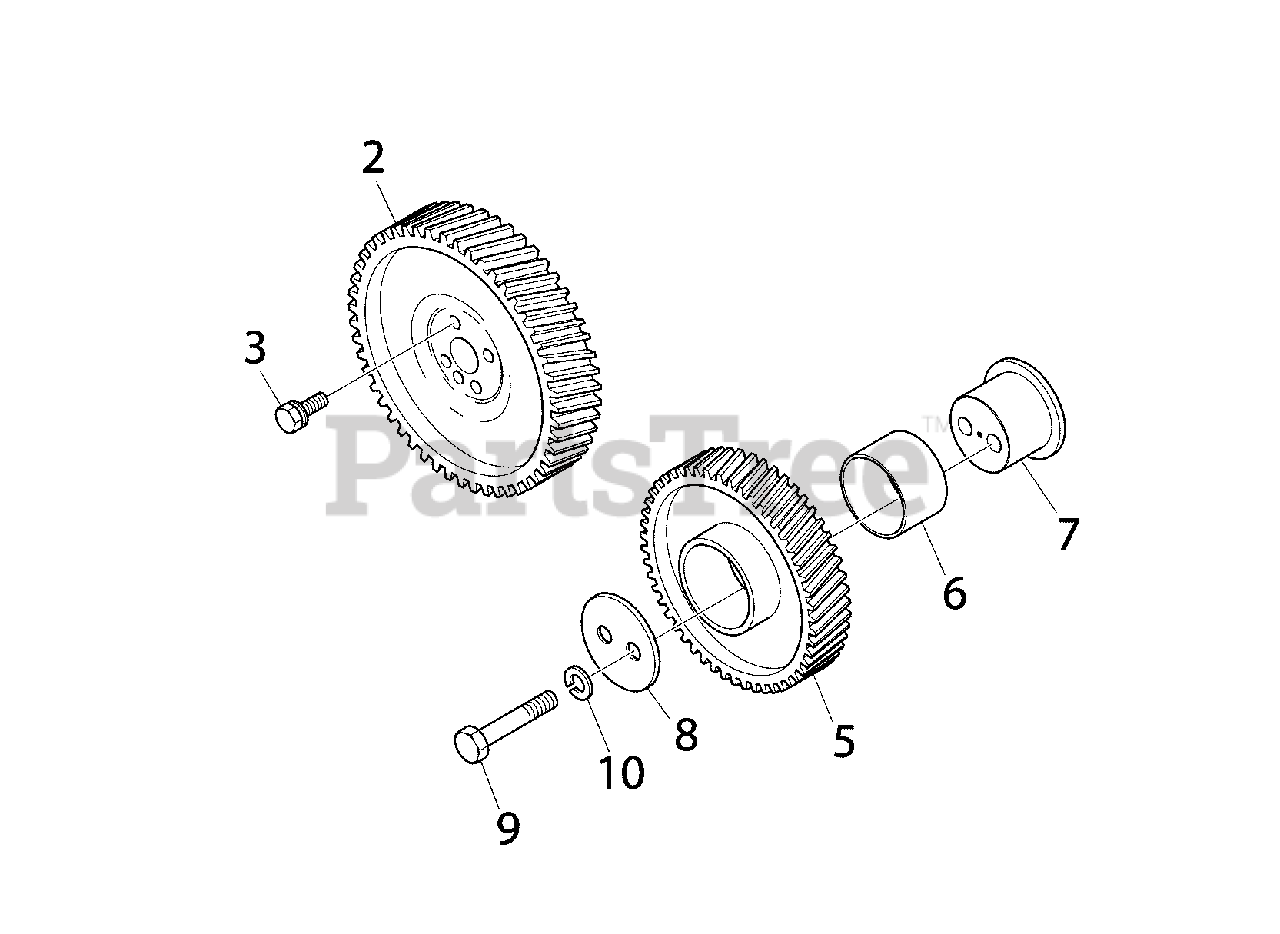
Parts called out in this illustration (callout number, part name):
2	* GEAR, CAMSHAFT
3	* BOLT
5	* GEAR, IDLER
6	* BUSHING, I/GEAR
7	* IDLE GEAR PIN
8	* WASHER, THRUST
9	* BOLT, HEX
10	* WASHER, SPRING
